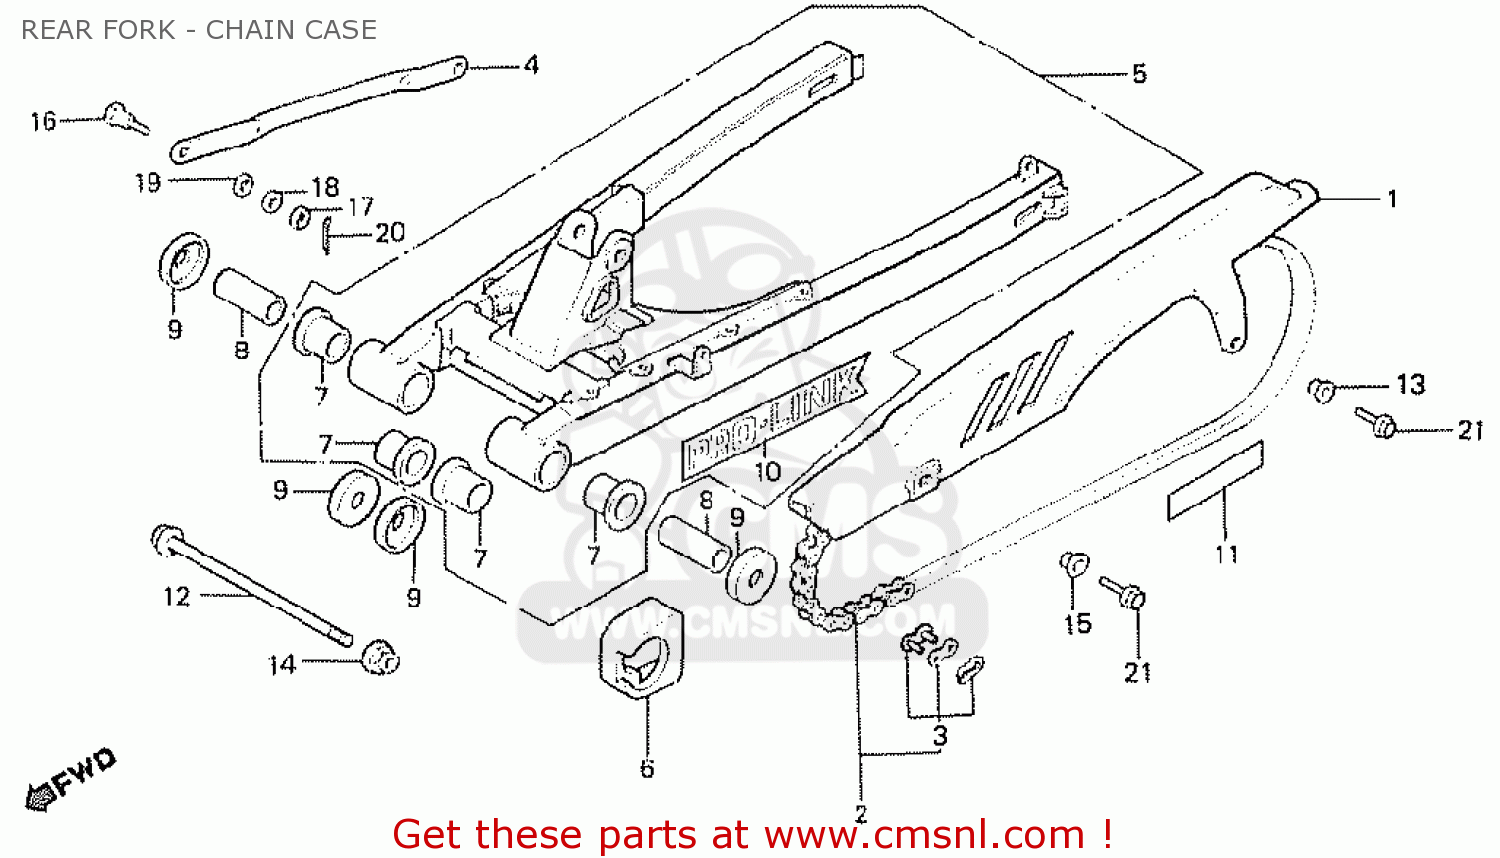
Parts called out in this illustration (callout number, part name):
1	CASE,DRIVE CHAIN
2	CHAIN,DRIVE
3	JOINT,DRIVE CHAIN
4	ARM,RR.BRK.STOPR.
5	FORK,RR.*NH-35M*
6	SLIDER,CHAIN
7	BUSH,REAR FORK
8	COLLAR.RR FORK
9	CAP,DUST SEAL
10	EMBLEM,RR.FORK
11	MARK, TIRE CAUTION
12	BOLT,RR FORK
13	COLLAR,REFLECTOR
14	NUT,AXLE U,14MM
15	WASHER,6X9
16	BOLT A,ARM STOPP
18	WASHER,PLAIN,8MM
19	SPG-WASHER 10MM
20	PIN,COTTER 2.0X15
21	BOLT, FLANGE,6X12
